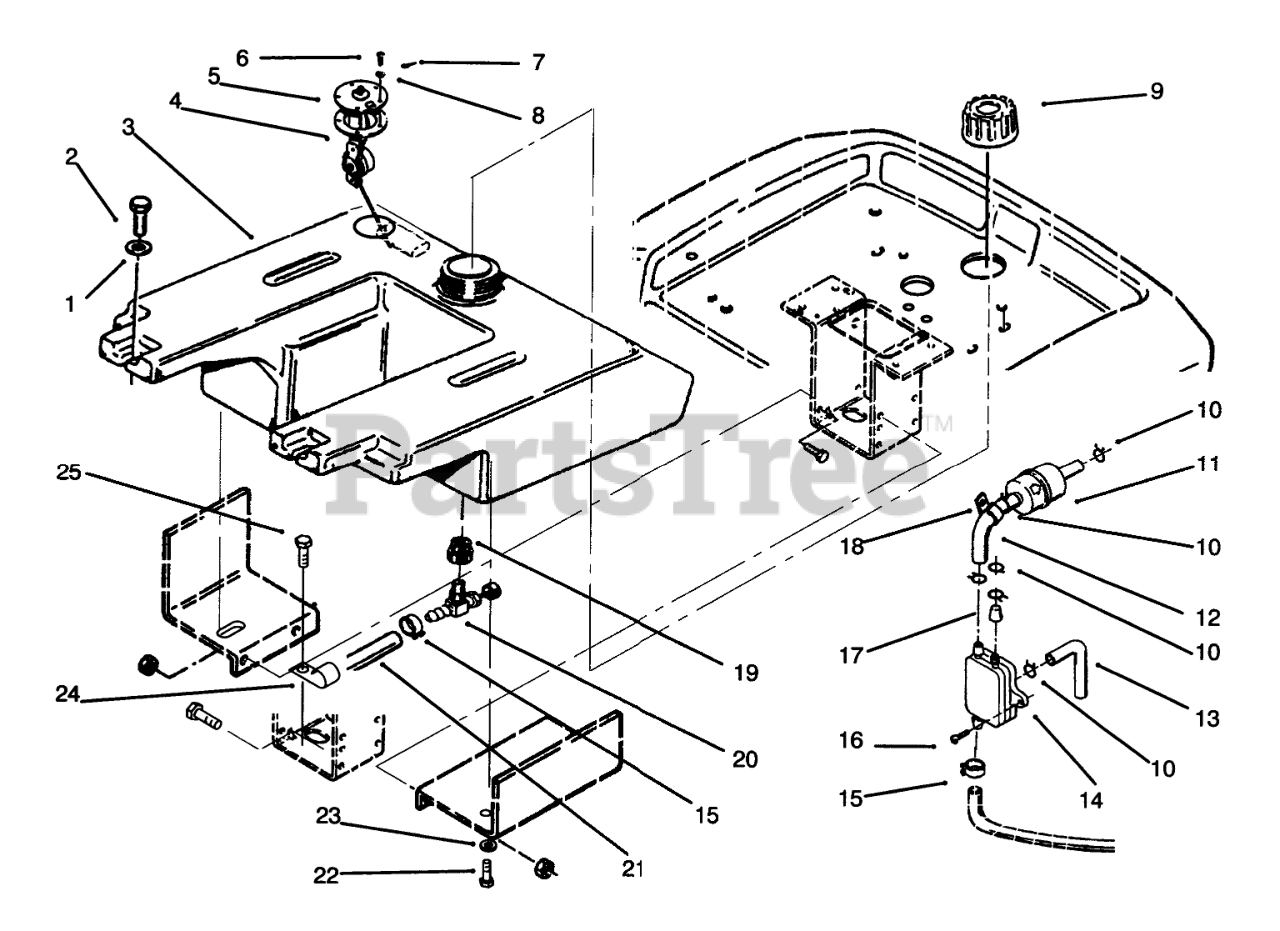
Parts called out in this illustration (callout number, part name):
1	WASHER-FLAT
3	Tank-Fuel (Incl. Ref.# 19 & 20)
4	GASKET-SENDER, FUEL
5	SENDER-FUEL LEVEL
6	Screw
7	TERMINAL-GROUND
8	WASHER-LOCK
9	GAS CAP ASM
10	CLAMP-HOSE
11	FILTER-FUEL
12	Hose
13	Hose
14	Fuel Pump
15	Clamp
16	SCREW-TAPPING PAN HD
17	Cap
18	CLAMP
19	BUSHING
20	VALVE-FUEL
21	FUEL HOSE 75" OF 6554
22	SCREW-HH
23	WASHER-LOCK
24	Clip
25	SCREW-HH, LOCK
